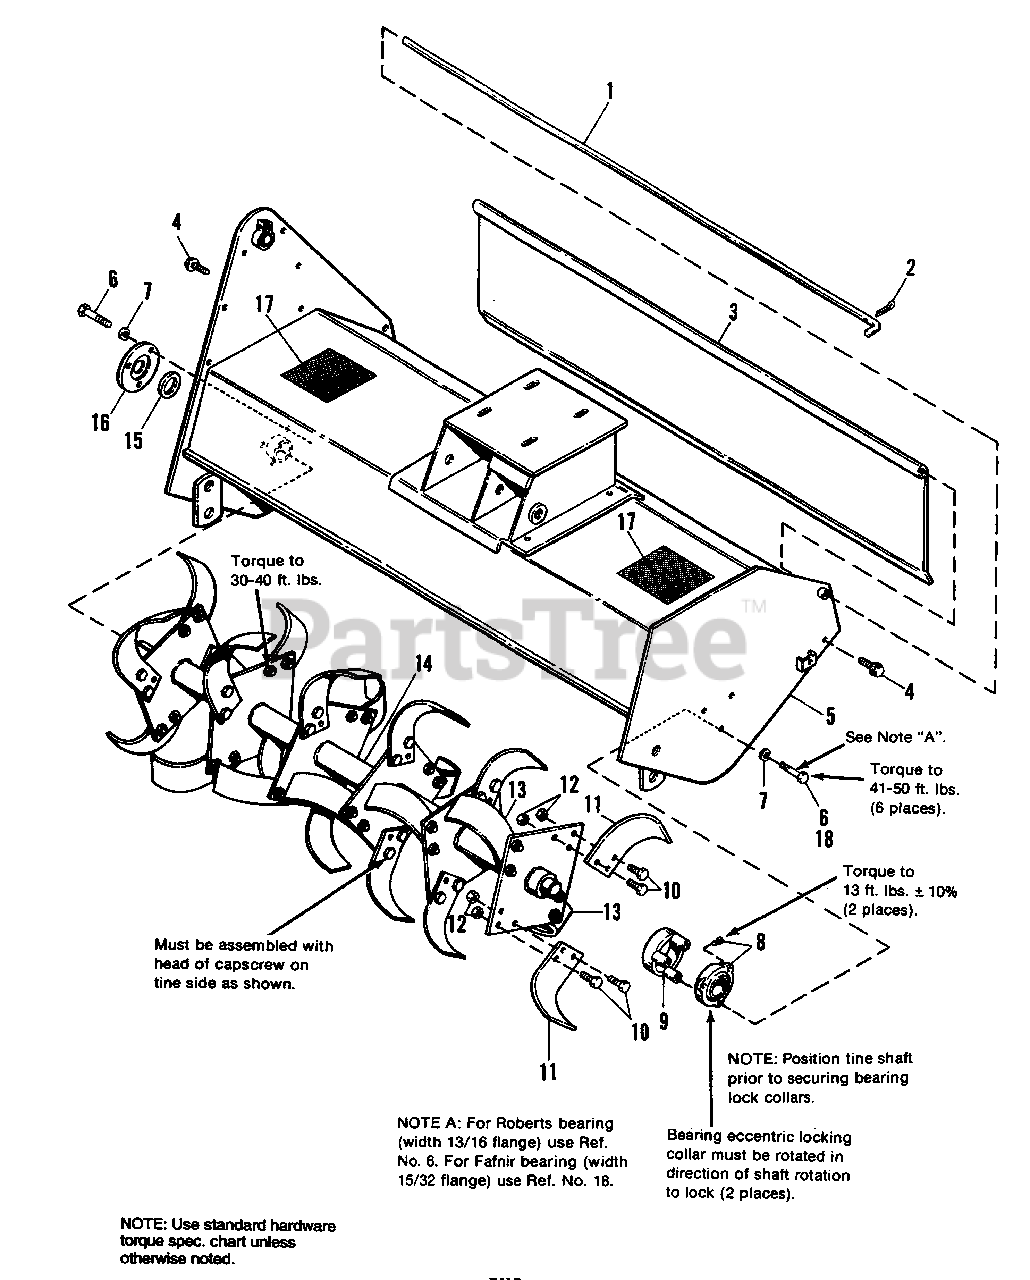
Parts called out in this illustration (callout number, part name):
1	ROD, Deflector
2	PIN, Cotter, 3/32 x 1
4	SCREW, Thd. Form., Taptite, 3/8-16 x 1-1/4
5	HOUSING ASSY.
6	CAPSCREW, Hex Head, 3/8-16 x 1-3/4
7	LOCKWASHER, 3/8
8	FLANGE, Bearing Kit
9	GUARD ASSY., Trash
10	CAPSCREW, Hex Hd., 3/8-16 x 1
11	TINE, LH.
12	LOCKNUT, Hex, 3/8-16
13	TINE, R.H.
14	SHAFT ASSY., Tine
16	RETAINER, Seal
17	DECAL, Danger
18	CAPSCREW, Hex Hd., 3/8-16 x 1-1/4
